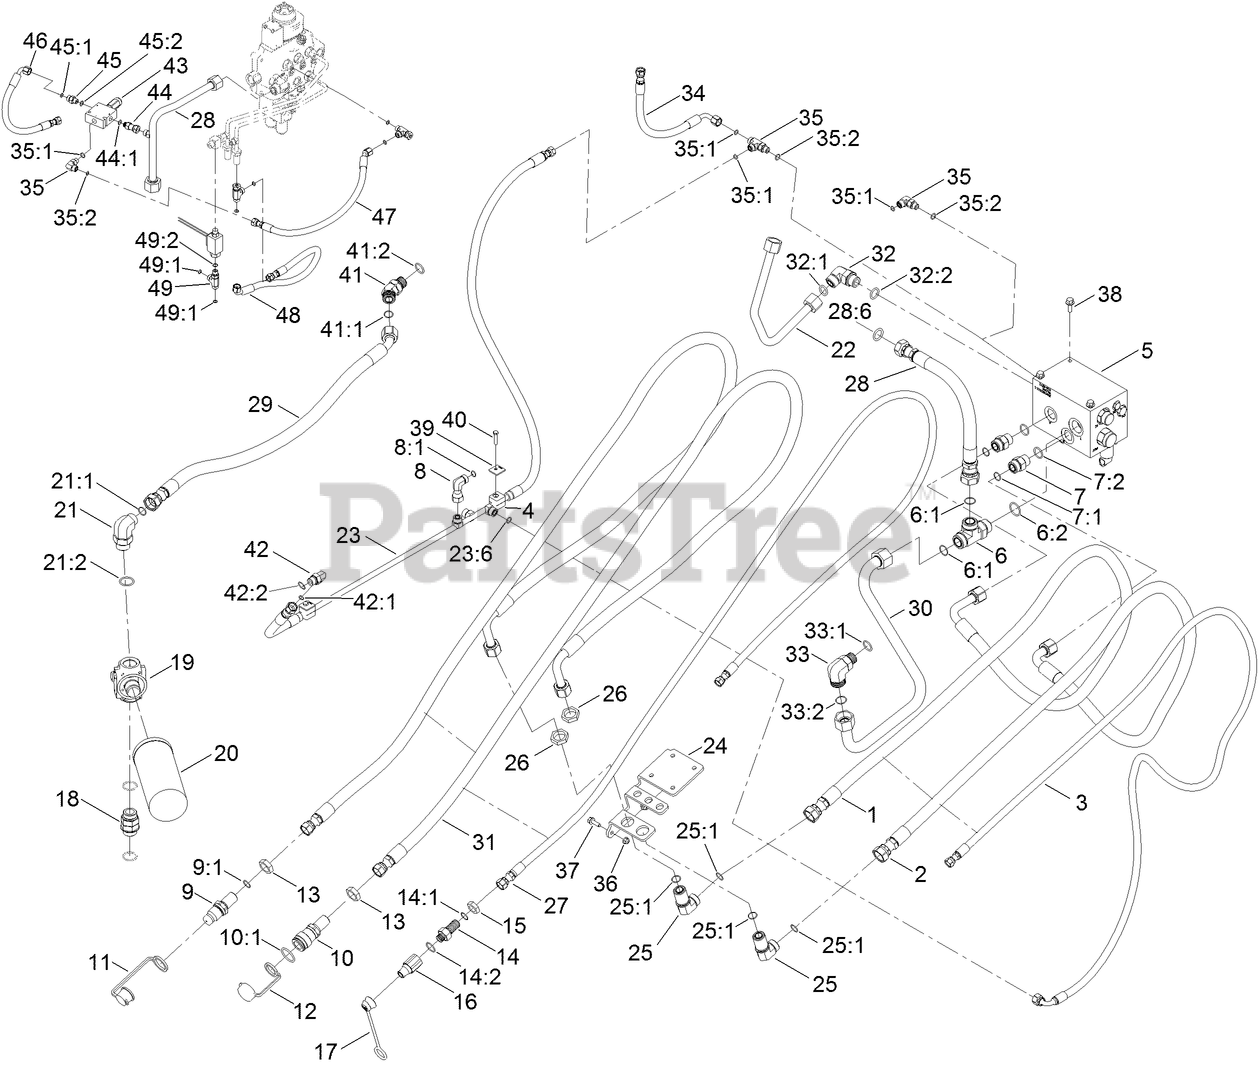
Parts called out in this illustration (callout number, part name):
1	HYD HOSE ASM
2	HYD HOSE ASM
3	HYD HOSE ASM
4	CLAMP-TUBE
5	AUX MANIFOLD ASM
6	FITTING-TEE
6:1	O-RING
6:2	O-RING
7	FITTING-HYD, STRAIGHT
7:1	O-RING
7:2	O-RING
8	FITTING-HYD
8:1	O-RING
9	BULKHEAD NIPPLE ASM
9:1	O-RING
10	BULKHEAD COUPLER ASM
10:1	O-RING
11	CAP-DUST, NIPPLE
12	CAP-DUST, COUPLER
13	NUT-LOCK, BULKHEAD
14	UNION-BULKHEAD
14:1	O-RING
14:2	O-RING
15	NUT-BULKHEAD
16	FITTING-QUICK COUPLING
17	CAP-DUST, NIPPLE
18	FITTING-STRAIGHT
19	HEAD-FILTER
20	ELEMENT-FILTER
21	FITTING-ELBOW 90
21:1	O-RING
21:2	O-RING
22	HYD TUBE ASM
23	HYD TUBE ASM
23:6	O-RING
24	MOUNT-CARRIER
25	FITTING-ELBOW 90
25:1	O-RING
26	NUT-BULKHEAD
27	HYD HOSE ASM
28	HYD TUBE ASM
28:6	O-RING
29	HYD HOSE ASM
30	HYDRAULIC TUBE ASM
31	HYD HOSE ASM
32	FITTING-ELBOW-90
32:1	O-RING
32:2	O-RING
33	FITTING-ELBOW 90
33:1	O-RING
33:2	O-RING
34	HYD HOSE ASM
35	FITTING-ELBOW, 90 DEG
35	FITTING-TEE
35:1	O-RING
35:2	O-RING
36	NUT-HF, NI
37	SCREW-HHF
38	SCREW-HHF
39	PLATE-CLAMP,TUBE
40	SCREW-HH
41	FITTING-45 DEG
41:1	O-RING
41:2	O-RING
42	FITTING-ELBOW, 90 DEG
42:1	O-RING
42:2	O-RING
43	VALVE-SEQUENCE
44	CONNECTOR-SWIVEL, STRAIGHT
44:1	O-RING
45	FITTING-STRAIGHT
45:1	O-RING
45:2	O-RING
46	HOSE ASM
47	HOSE-HYD
48	HOSE-HYD
49	FITTING-TEE
49:1	O-RING
49:2	O-RING
